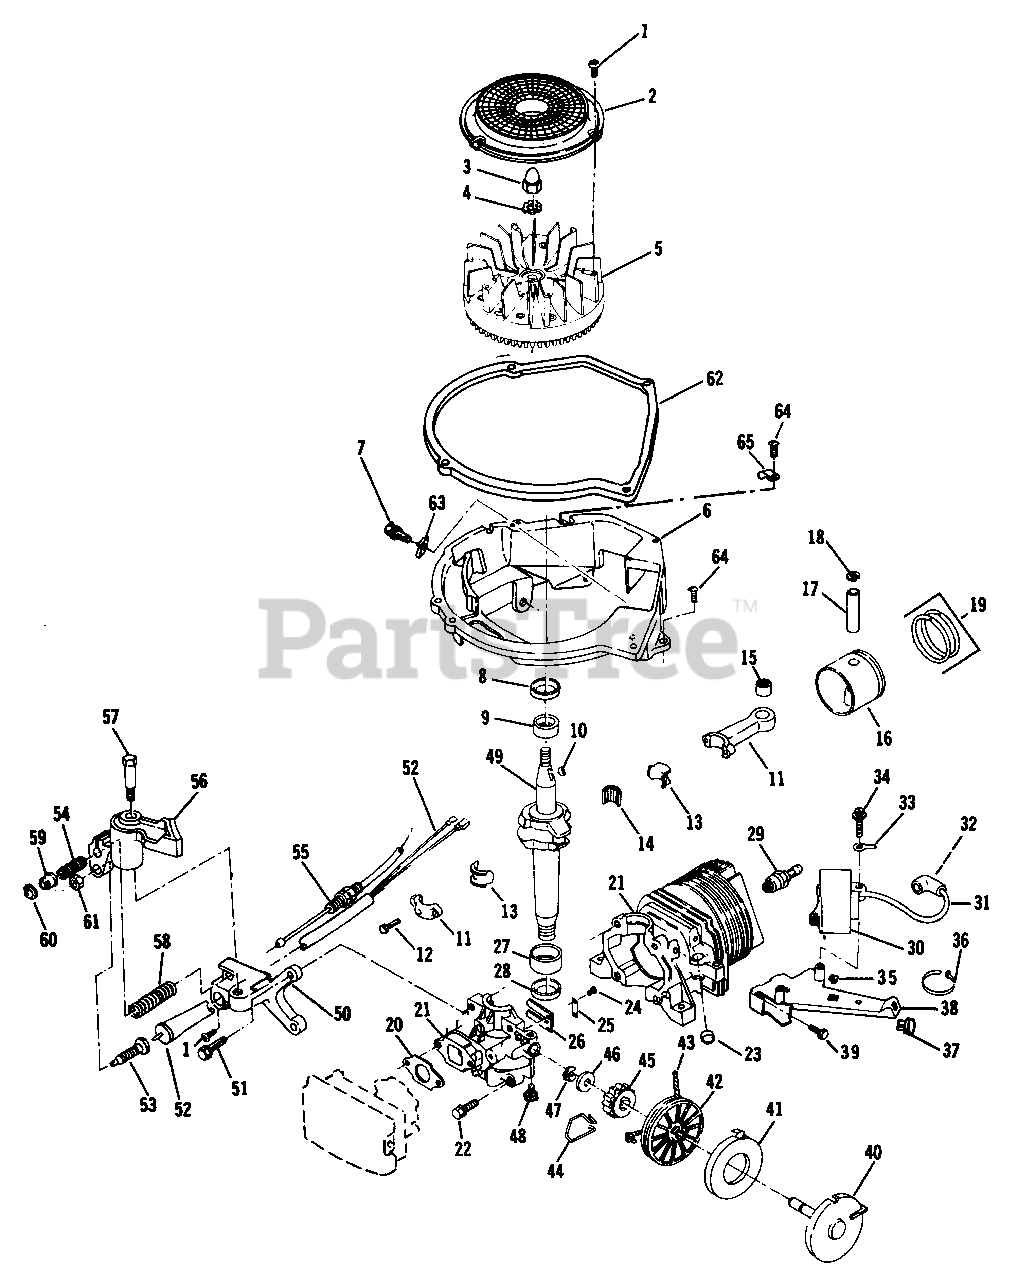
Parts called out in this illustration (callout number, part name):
1	Screw-Flywheel Screen and Switch
2	Screen-Flywheel
3	Nut-Flywheel
4	Lockwasher
5	Flywheel Assembly
6	Base-Shroud
8	Oil Seal-Upper
9	Bearing-Main-Upper
10	Key-Flywheel
11	Conn. Rod Assembly
12	Screw-Cap
13	Liner Split
14	Needle Bearing Set
15	Bearing Assembly
16	Piston and Ring Set
17	Wrist Pin
18	Retaining Ring
19	Ring Set
20	Gasket-Carburetor to Crankcase Cover
21	Cylinder and Crankcase Cover Assembly
22	Screw-Cover to Crankcase
24	Screw-Reed to Crankcase
25	Plate-Reed Hold Down
27	Bearing-Main-Lower
28	Oil Seal-Lower
29	Spark Plug
30	C.D. Ignition Module and Lead Assembly
31	High Tension Lead and Cover Assembly
32	Spring Terminal
33	Terminal-Ground Lead
34	Screw-C.D. Mounting
35	Grommet-C.D. Bracket
36	Tie Strap
37	Grommet
38	Bracket-Ignition Mounting
39	Screw
40	Spring Cup and Pin Assembly
41	Spring and Retainer Assembly
44	Spring-Drag
47	Retainer
48	Set Screw-Starter Assembly
49	Crankshaft
50	Bracket-Brake
51	Screw-Brake Mtg. Brkt.
52	Brake Switch Assembly
53	Plunger
54	Spring-Brake
55	Control Cable Assembly
56	Brake Assembly
57	Bolt-Shoulder
58	Spring-Cable Retainer
59	Actuator-Brake Lever
60	Retainer
61	Nut
62	Spacer-Shroud to Base
63	"J" Clip
64	Screw-Shd. Base to C.D. Brkt. and Clamp to Base
